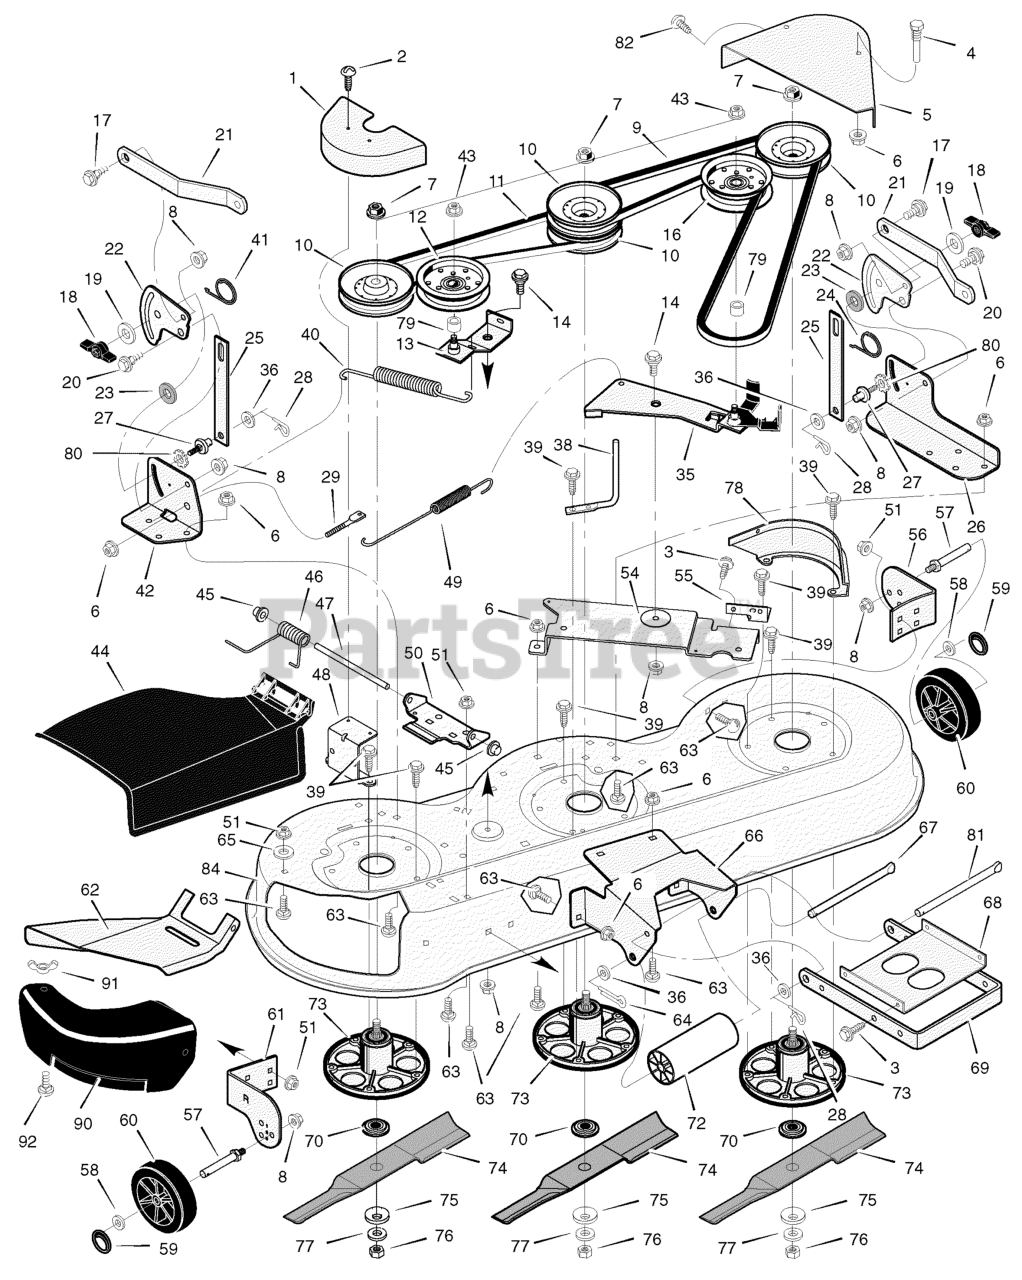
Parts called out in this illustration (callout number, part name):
1	Cover, Right Pulley
3	Screw
4	Guide, Belt
5	Cover, Left Pulley
6	Nut, Hex
7	Nut, Flange
8	Nut, Flange
9	Belt, Primary
10	Pulley
11	Belt, Secondary
12	Pulley, Idler
13	Arm, Idler
14	Bolt, Shoulder
16	Pulley, Idler
17	Bolt, Shoulder
19	Washer
20	Bolt, Shoulder
21	Bracket, Rear Suspension
22	Plate, Suspension
23	Pad, Friction
24	Spring
25	Link, Lift
26	Bracket, Left Lift
27	Pin, Hanger
28	Pin, Hair
29	Rod, Adjuster
35	Idler, Arm
36	Washer
38	Guide, Belt
39	Screw
40	Spring, Extension
41	Spring, Torsion
42	Bracket, Suspension
43	Nut
44	Deflector, Chute
45	Push On Cap
46	Spring, Torsion
47	Rod, Deflector
48	Bracket, Cover
49	Spring, Extension
50	Bracket, Hinge
51	Nut, Flange
54	Plate, Brake Arm
55	Bracket, Brake Plate
56	Bracket, Left Gauge Wheel
58	Washer
59	Ring, Locking
60	Wheel, Gauge
61	Bracket, Right Gauge Wheel
62	Deflector, Inside
63	Bolt, Carriage
64	Pin, Cotter
65	Washer
66	Bracket, Front Deck
67	Rod, Hanger
68	Stiffener
69	Bracket, Suspension
70	Adapter, Blade
72	Roller
73	Housing, Jackshaft
75	Washer, Belleville
76	Nut
77	Washer
78	Bracket, Pulley Cover
79	Spacer
80	Washer
81	Rod, Hanger
82	Screw
84	Housing, Mower
90	Cover, Mulch
91	Wingnut
92	Bolt, Carriage
